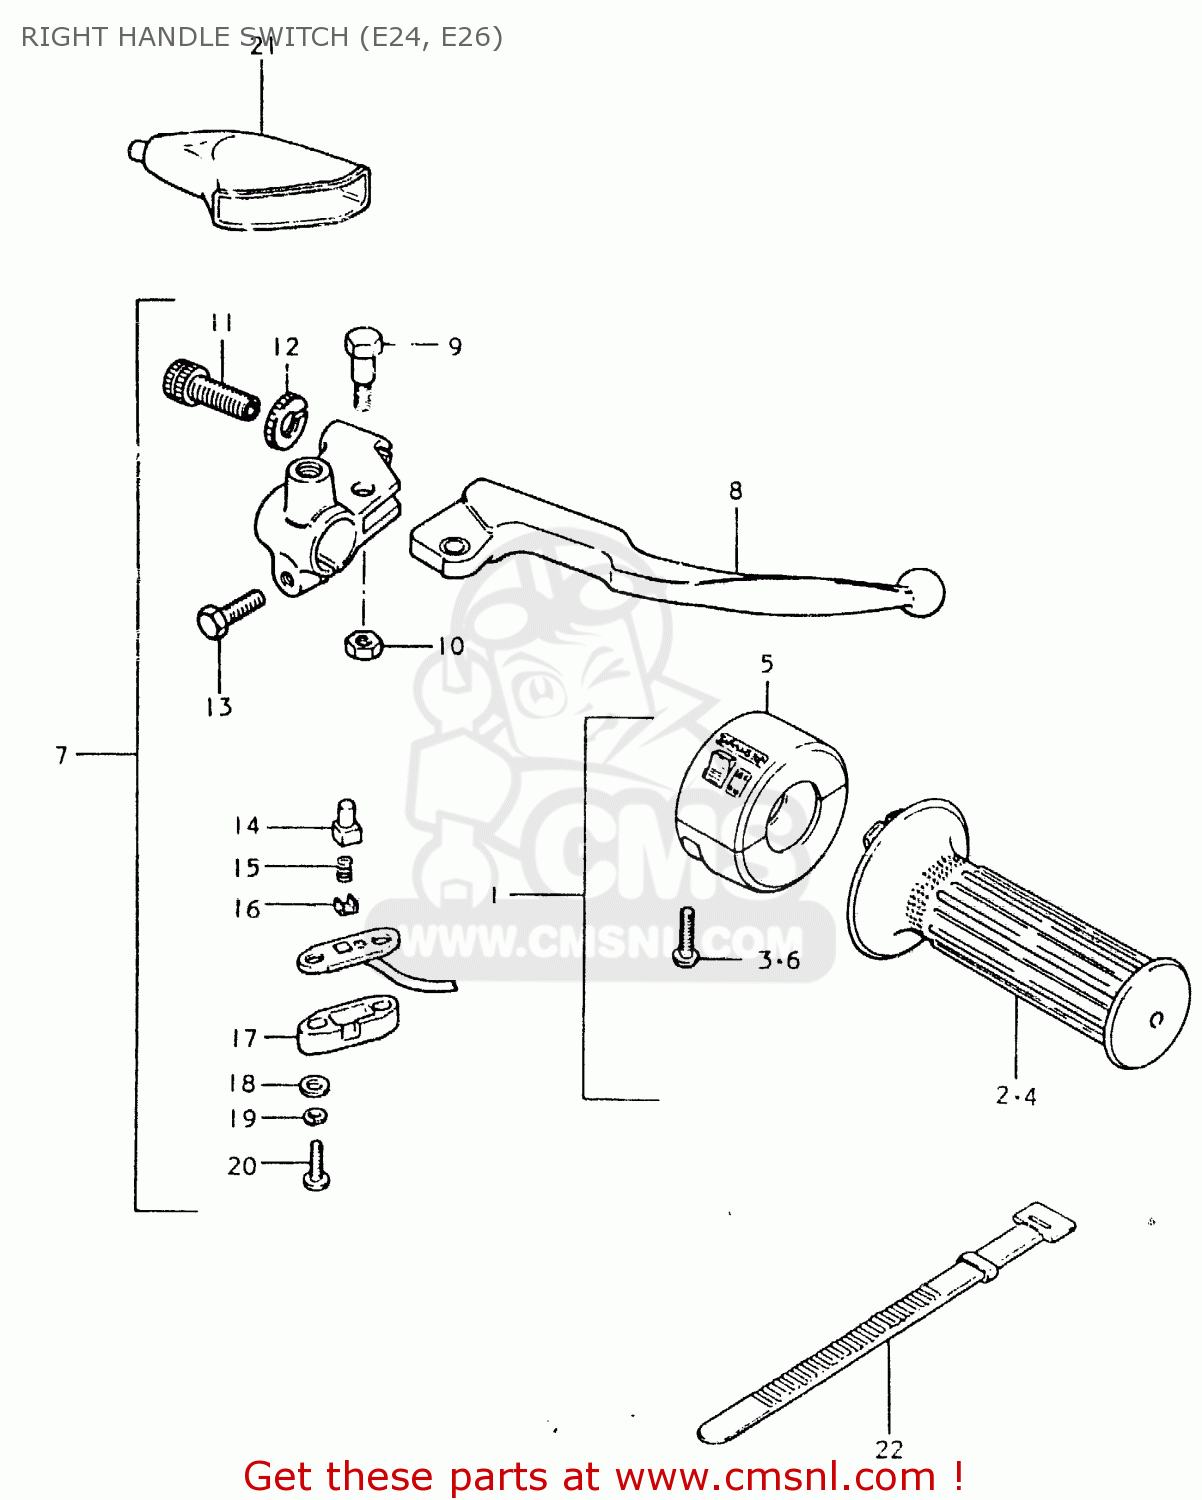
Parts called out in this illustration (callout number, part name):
1	CASE ASSEMBLY,THROTTLE
2	GRIP,THROTTLE
3	SCREW
4	GRIP,THROTTLE
5	CASE ASSY,THROTTLE
6	SCREW
7	LEVER ASSY,BRAKE
8	LEVER,BRAKE
9	BOLT,LEVER
10	NUT 6MM
11	ADJUSTER,CABLE
12	NUT,CABLE ADJUSTER
13	BOLT
14	HOLDER
15	SPRING
16	PLATE
17	COVER,FR BK TERMINAL BASE
18	WASHER
19	LOCK WASHER
20	SCREW
21	COVER,CLUTCH LEVER
22	CLAMP(L:120)
